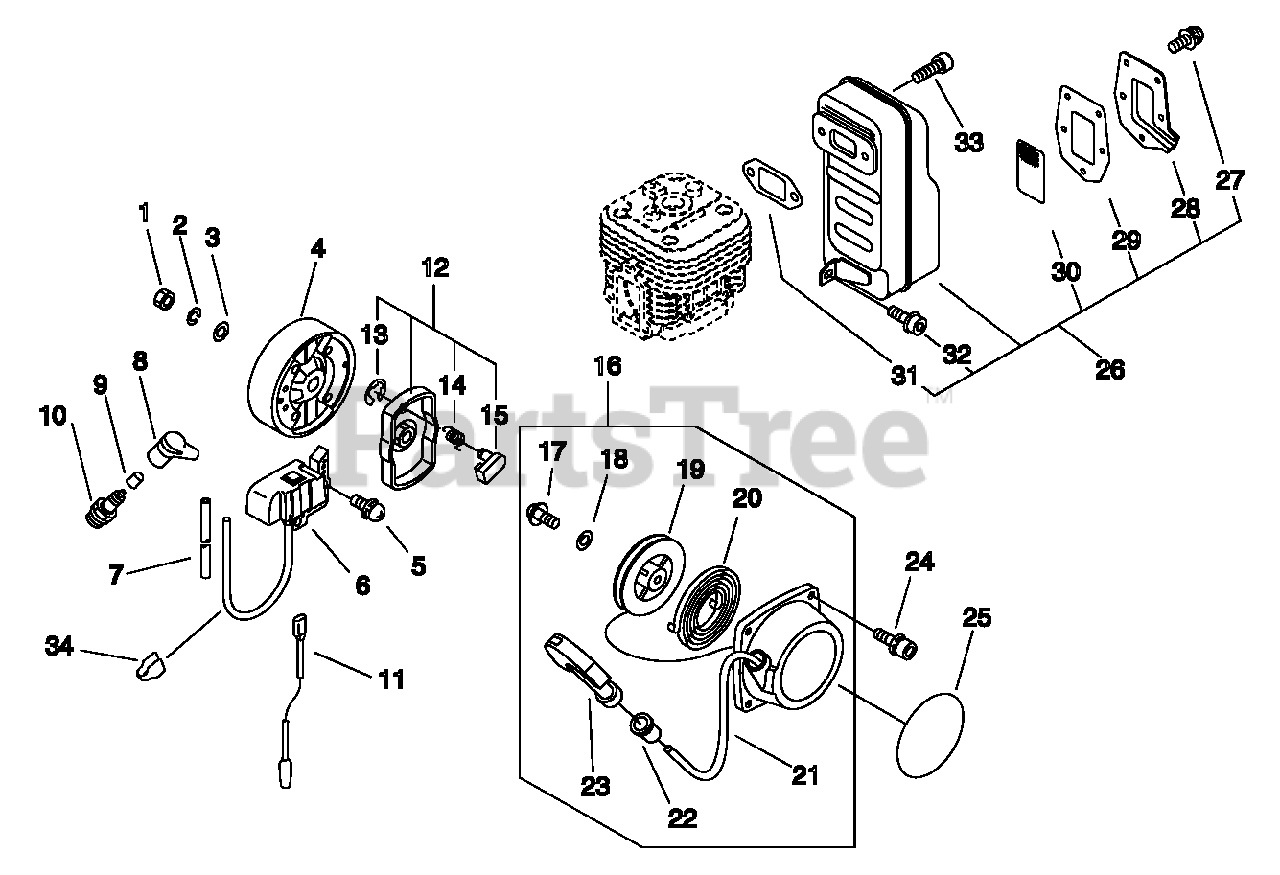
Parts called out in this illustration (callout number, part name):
1	NUT - 10
2	LOCKWASHER - 10
3	WASHER - 10
4	FLYWHEEL
5	SCREW - 5X18
6	COIL, IGNITION
7	TUBE - VINYL
8	CAP, SPARK PLUG
9	TERMINAL, SPARK PLUG CAP
10	SPARK PLUG -- BPMR-8Y
12	STARTER PAWL ASSY
16	STARTER ASSY
24	SCREW - 5X18
25	LABEL - ECHO
26	MUFFLER ASSY
27	SCREW - 4X10
28	GUIDE, EXHAUST
29	GASKET, EXHAUST
30	SCREEN, SPARK ARRESTOR
31	GASKET, EXHAUST
32	SCREW - 5X16
33	SCREW - 6X20
